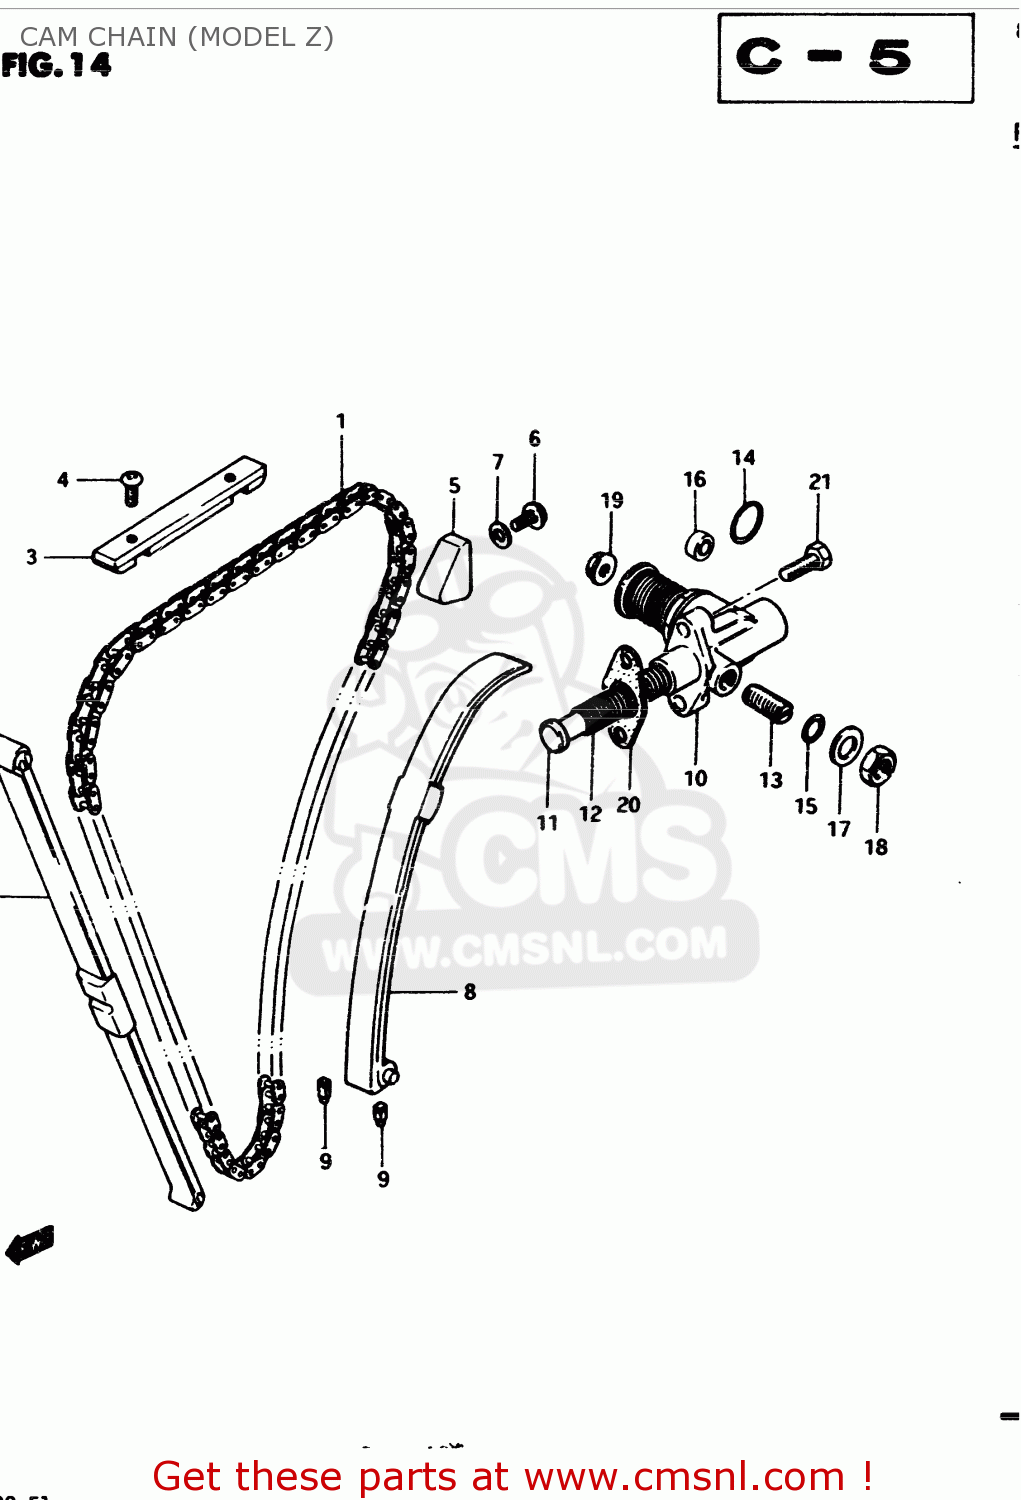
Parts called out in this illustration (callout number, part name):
1	CHAIN,CAMSHAFT DRIVE(120L)
2	GUIDE,CAM CHAIN NO.1
3	GUIDE,CAM CHAIN NO.3
4	SCREW
5	GUIDE,CAM CHAIN
6	BOLT
7	WASHER
8	TENSIONER,CAM CHAIN
9	CUSHION,CAM CHAIN TENSIONER
10	ADJUSTER,CAM CHAIN TENSIONER
11	ROD,PUSH
12	SPRING
13	SCREW
14	O RING(D:2.4,ID:20.8)
15	O RING(D:1.9,ID:5.7)
16	SEAL,OIL(10X16X4)
17	WASHER
18	NUT
19	NUT
20	GASKET,TENSIONER ADJUSTER (MCA)
21	SCREW (6X25)
